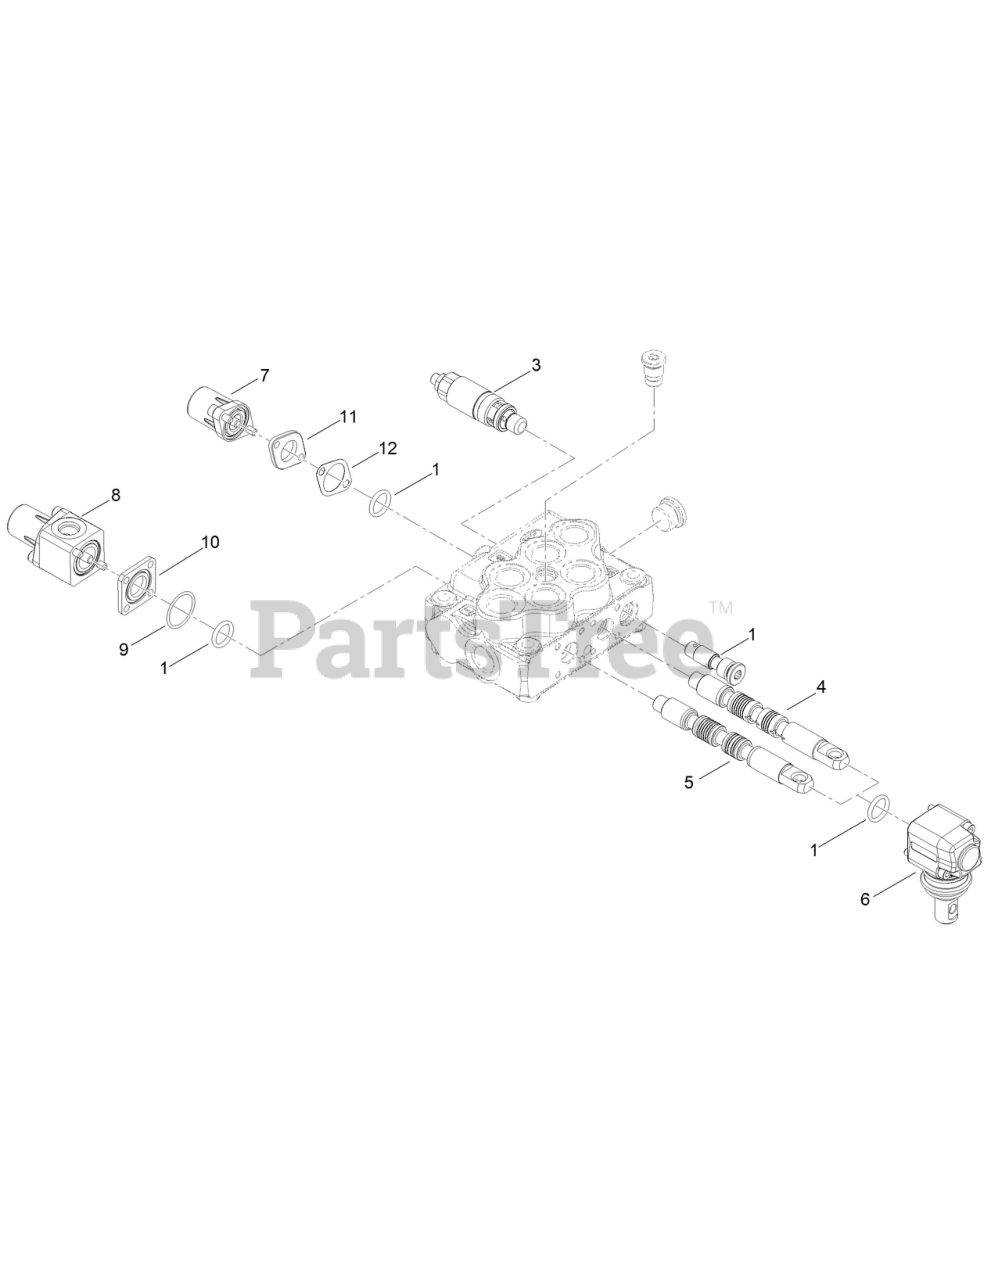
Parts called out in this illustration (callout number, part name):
1	SEAL-VALVE
3	VALVE-RELIEF
4	SPOOL-VALVE
6	LEVER KIT
7	SPRING RETURN KIT
8	SWITCH SPRING RETURN KIT
9	SEAL-RETURN
10	SPACER-SQUARE
11	SPACER-SPRING RETURN
12	GASKET-RETURN
